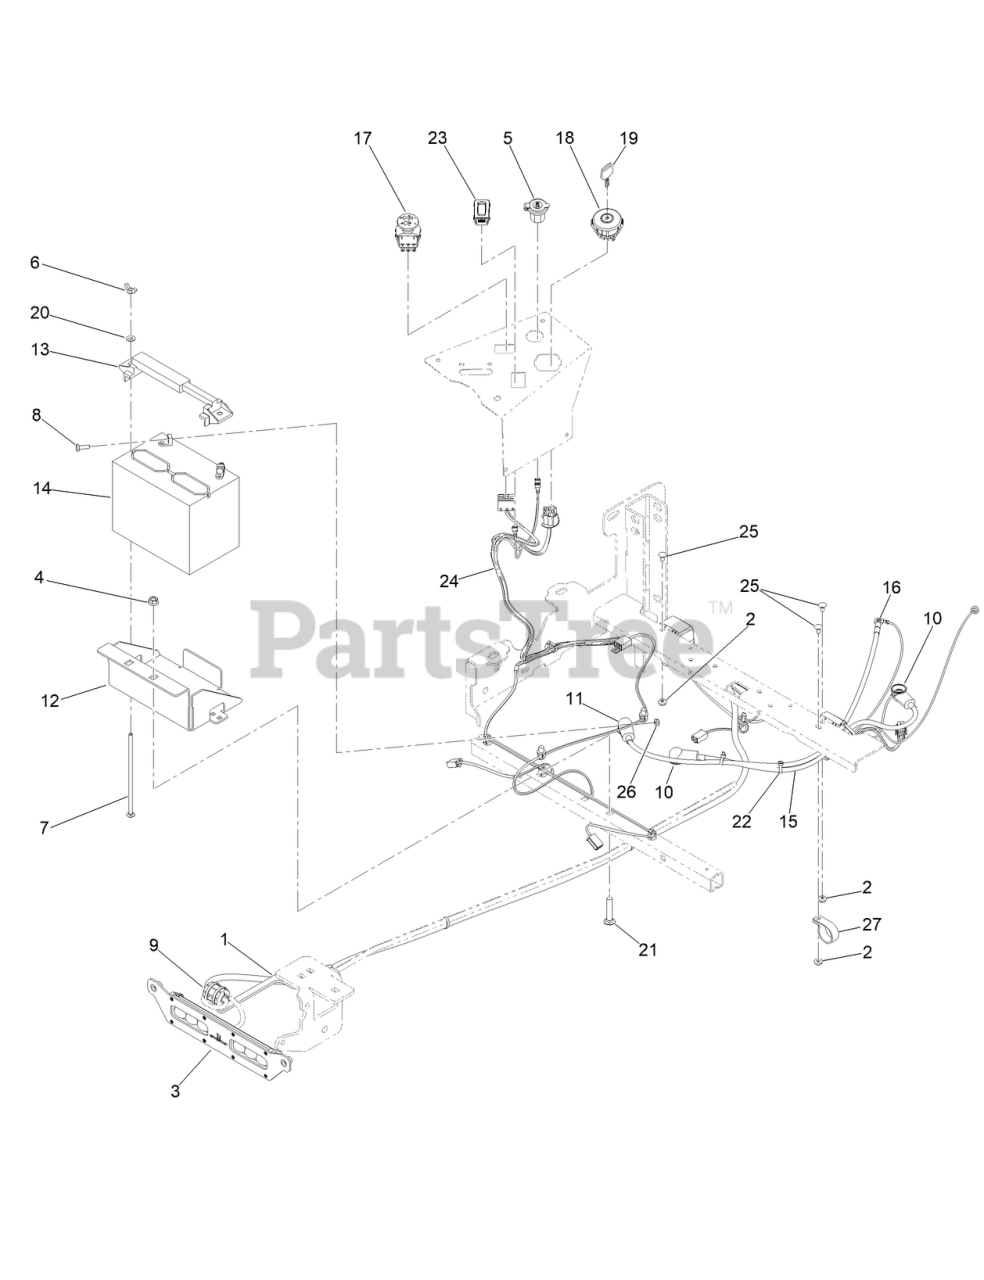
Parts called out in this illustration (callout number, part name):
1	FAIR-RITE BRACKET PAINTED
2	1/4-20 HEX FLANGE NUT
3	SPLIT BEAM W/NON-LIGHTD HELMET LIGHT BAR
4	3/8-16 HEX FLANGE NUT W/SERR ZINC YELLOW
5	12 VOLT AUXILLIARY PLUG
6	NUT-WING
7	1/4-20 X 7 CARRIAGE BOLT ZINC
8	SCREW-HH
9	FAIR-RITE ROUND CABLE SNAP-IT SIZE B
10	3.15 LGTH STRAIGHT INSUL TERM COVER RED
11	STRAIGHT INSULATING TERMINAL COVER
12	MWR BATTERY BOX BLACK
13	BATTERY HOLD DOWN
14	MWR START BATTERY 350CCA
15	MWR POSITIVE BATTERY CABLE 25IN
16	MWR NEGATIVE CABLE 28
17	PTO SWITCH
18	IGNITION SWITCH
19	2023 MWR KEY
20	WASHER-FLAT
21	SCREW-CARR
22	TIE-CABLE
23	HOUR METER
24	HARNESS-WIRE
25	SCREW-CARR
26	NUT-HF
27	1-1/4IN CUSHIONED LOOP CLAMP BLACK
